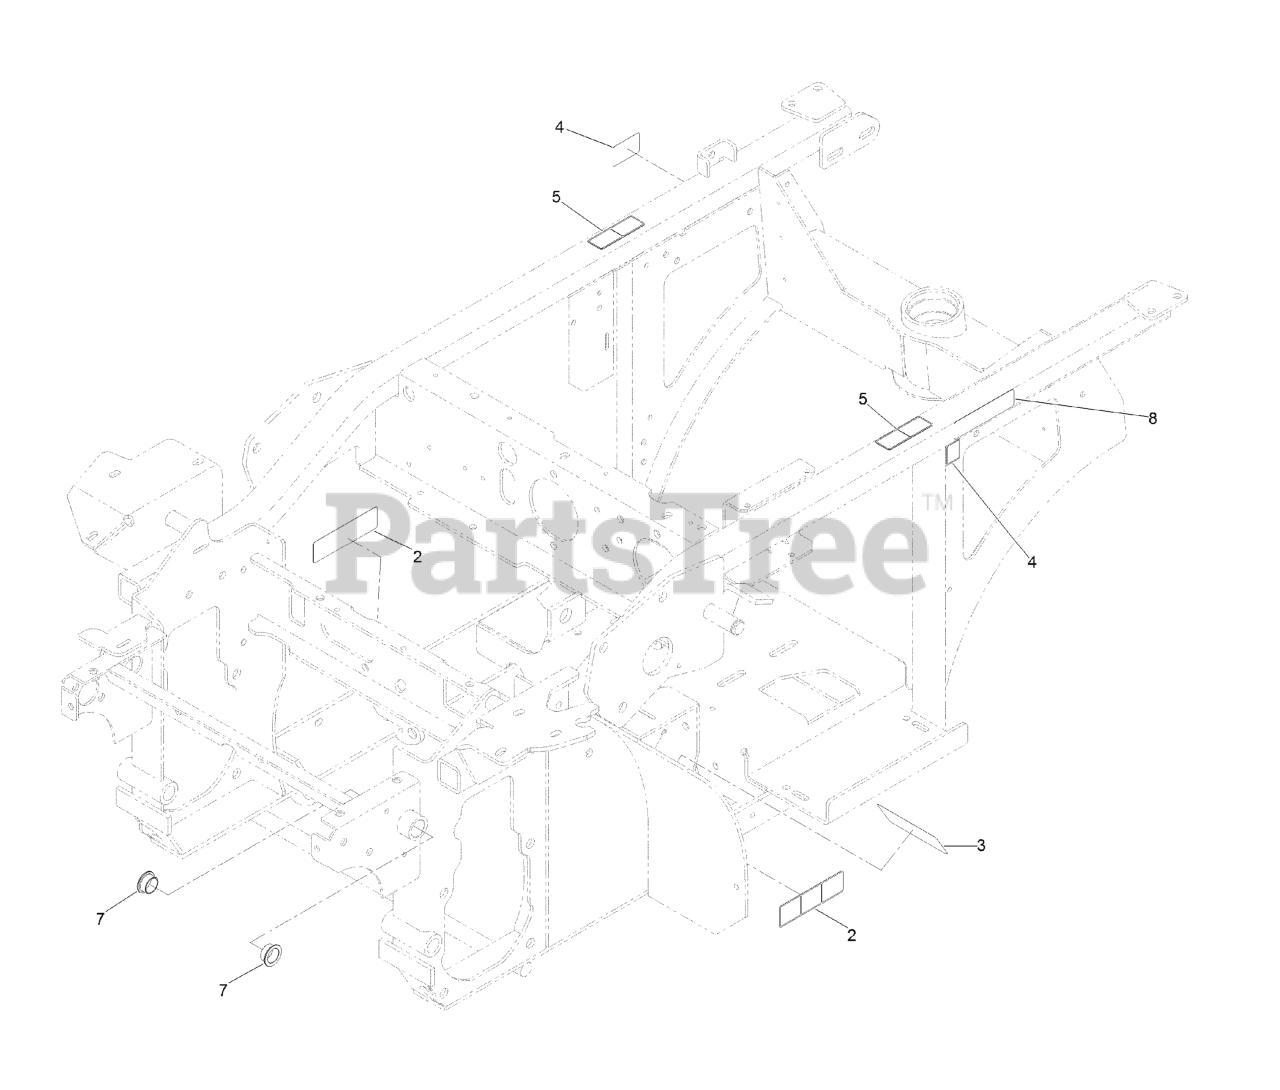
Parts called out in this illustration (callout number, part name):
2	DECAL-COVER, MISSING
3	Decal-Adjustment, Clutch
4	DECAL-WARNING
5	DECAL-WARNING, PINCH POIN
7	BUSHING-BRONZE
8	DECAL-ARRESTOR, SPARK
